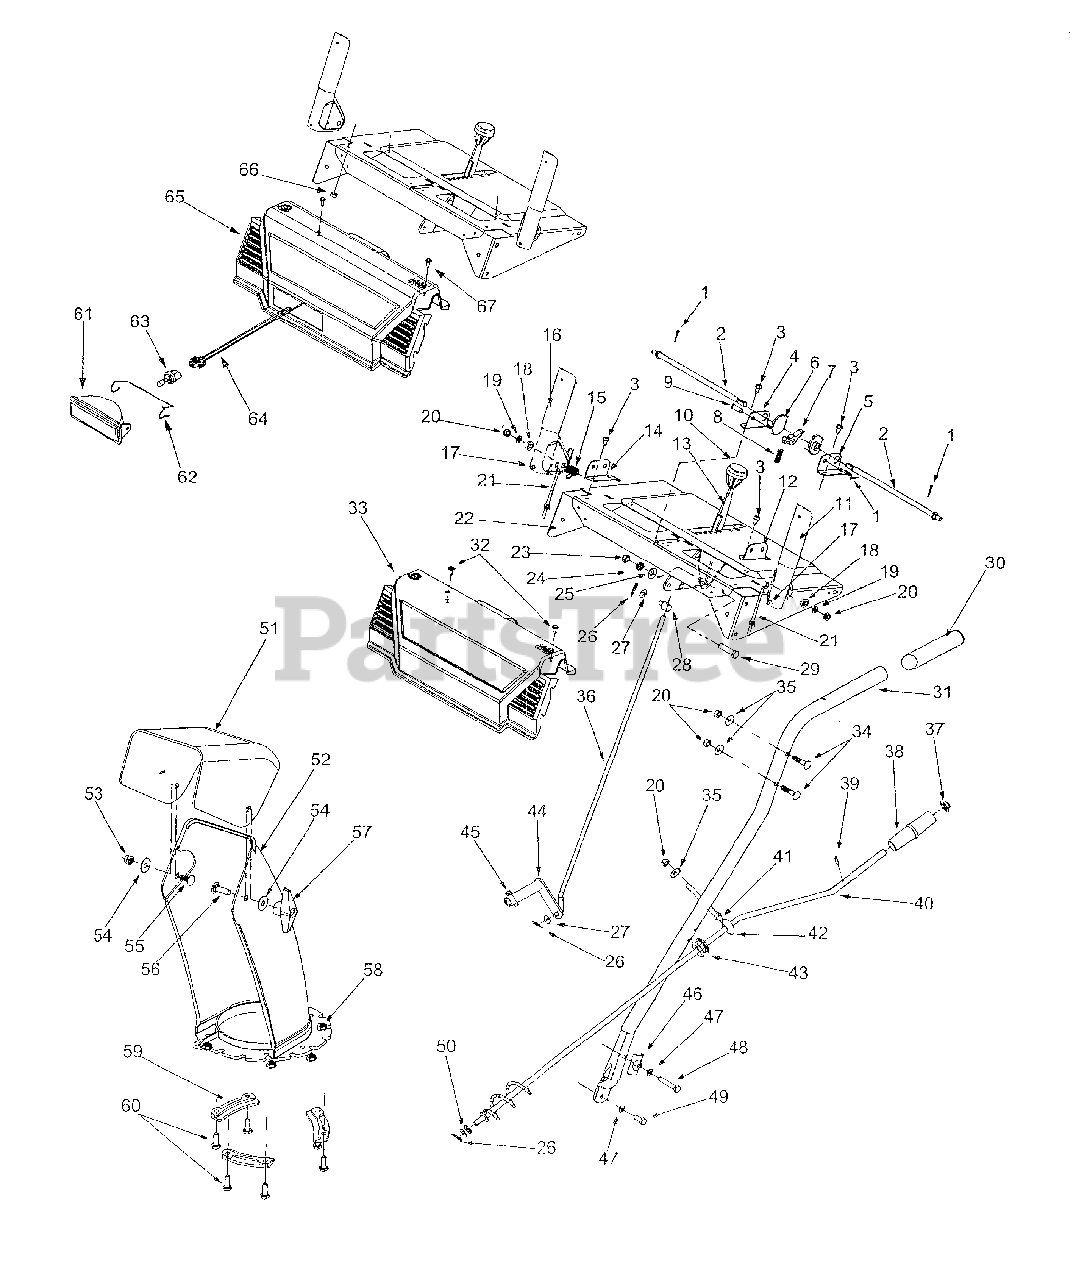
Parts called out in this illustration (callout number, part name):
1	Cotter Pin
3	Hex Washer Screw 1/4-20 x .5
4	Handle Support Bracket - RH
5	Handle Support Bracket - LH
6	Cam Lock Handle
7	Handle Lock Pawl
8	Compression Spring
9	Clevis Pin
11	Handle Assy - LH
13	Shift Handle
14	Handle Support Bracket- RH
15	Torsion Spring
16	Handle Assy - RH
17	Rubber Bumper
18	Washer
19	Lock Washer 5/16
20	Hex Nut 5/16-18
21	Cable
24	Compression Spring
25	Bell Washer
26	Cotter Pin
27	Flat Washer 5/16
28	Ferrule
29	Hex Cap Screw 3/8-24 x 1.50
31	Handle - RH
31	Handle - LH
32	Hew Washer Screw
33	Handle Panel
33	Handle Panel w/ Top Light
34	Carriage Bolt 5/16-18 x 1.50
35	Bell Washer .340 ID x .872 OD
36	Shift Rod
37	Push Cap
38	Chute Knob
39	Roll Pin
40	Chute Crank
41	Hex Nut 5/16 - 18
42	Chute Crank Eyebolt
43	Rubber Grommet
44	Shift Arm Assembly
45	Hex Washer Screw 1/4-20 x 1.0
46	Handle Tab
47	Lock Washer 5/16
48	Hex Cap Screw 5/16-18 x 1.75
49	Hex Cap Screw 5/16-18 x .75
50	Flat Washer
51	Upper Chute
52	Lower Chute
53	Hex Lock Nut 5/16-18
54	5/16 Washer
55	Carriage Bolt 5/16-18 x .75
56	Carriage Screw 5/16-18 x 1.0
57	Knob
58	Hex Lock Nut 1/4-20
59	Flange Keeper
60	Hex Cap Screw 1/4-20 x .75
61	Lens Housing Assembly
62	Headlight Retaining Wire
63	Halogen Light
64	Light Harness
65	Panel w/light
66	Hex Nut 1/4-20
67	Hex Washer Screw #10-16 x .625
